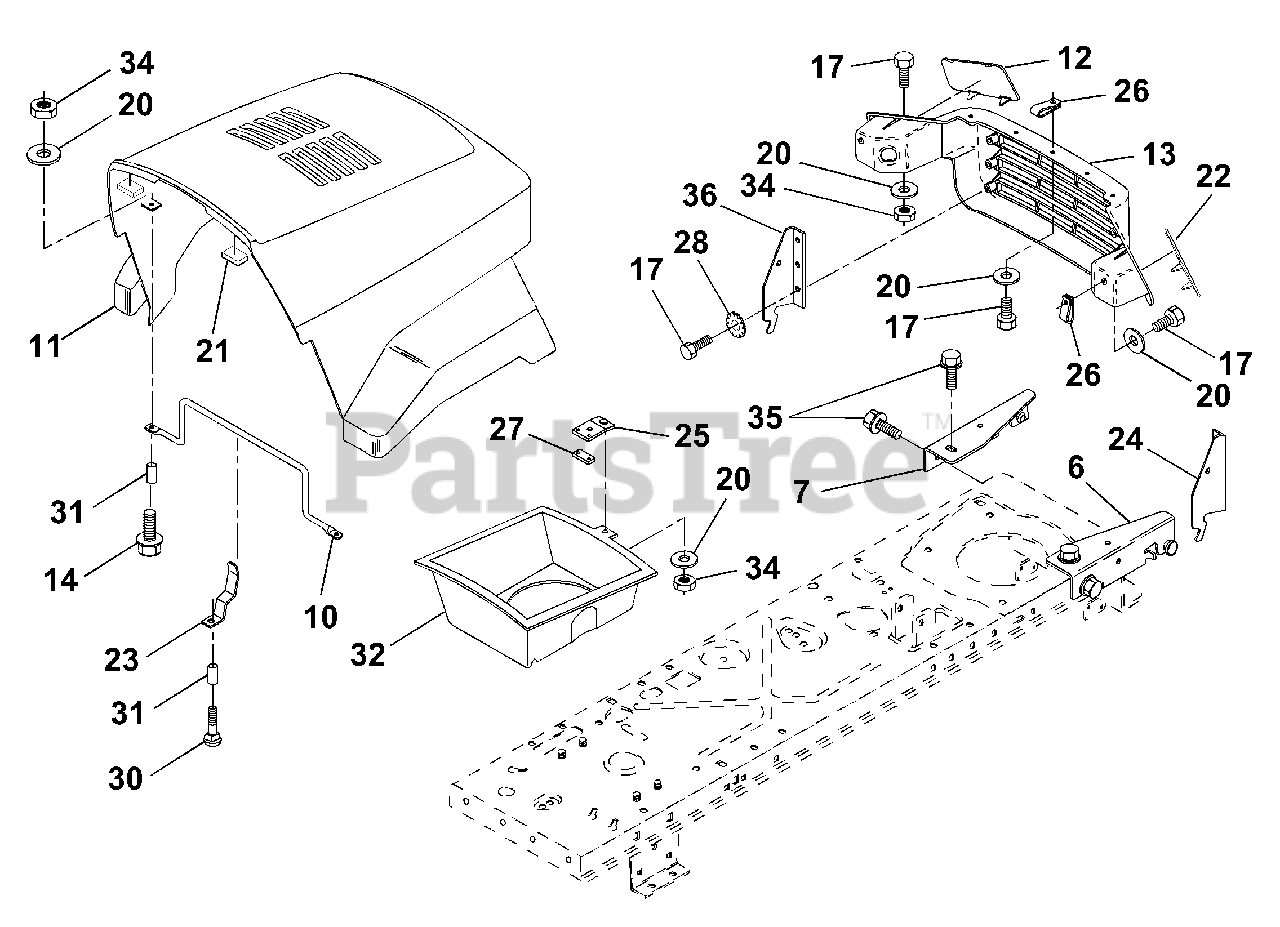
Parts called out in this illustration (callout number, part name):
6	Bracket Asm. Pivot Hood RH
7	Bracket Asm. Pivot Hood LH
10	Brace Hood
13	Grille
14	Bolt Hex Fin 1/4-20 Unc x 1-1/2
17	Bolt Fin Hex 1/4-20 x 5/8
20	Washer 9/32 x 3/4 x 16 Ga.
21	Bumper Hood
23	Latch Hood
24	Bracket Pivot Hood RH
25	Clip Asm. Duct Air
26	Clip Tinnerman
27	Clip Tinnerman
28	Washer Lock Ext Tooth
30	Bolt RDHD Sht Nk 1/4 - 20 x 1-3/8
32	Duct Air Hood
34	Nut Keps 1/4-20
35	Screw Thdrol 5/16-18 x 3/4
36	Bracket Pivot Hood LH
